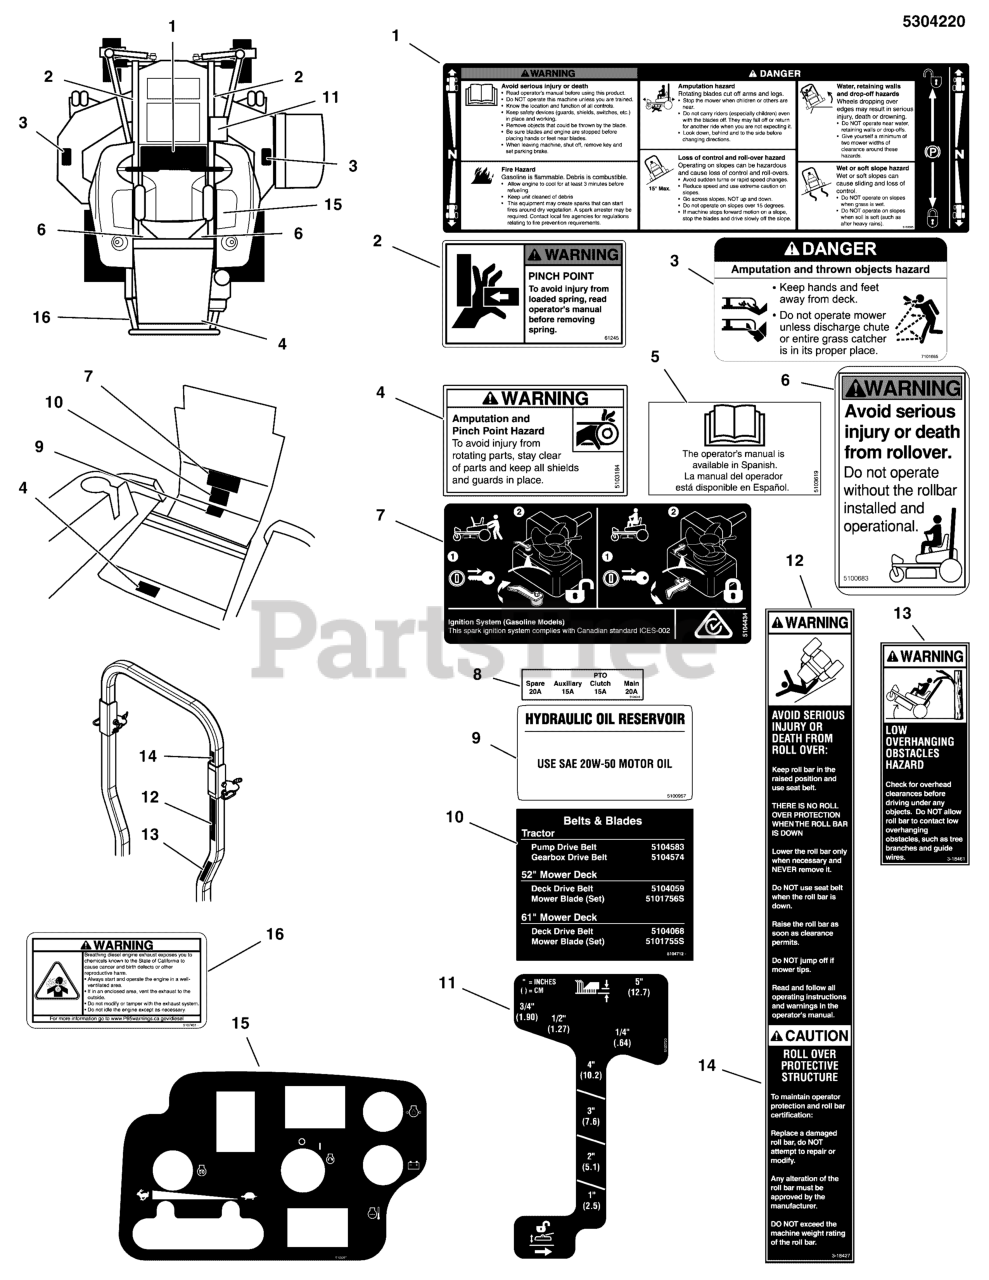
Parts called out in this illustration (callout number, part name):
1	DECAL, MAIN SAFETY
2	DECAL, Pinch Point
3	DECAL, DANGER DO NOT OPERATE W/O DEFLECT
4	DECAL, WARNING, HAND IN BELT, ENG ONLY
5	DECAL, MANUAL AVAILABLE IN SPANISH
6	DECAL, Warning, ROLL BAR
7	DECAL, TRANSAXLE RELEASE, ZT4400
8	DECAL, FUSE LOCATION, 20-15-15-20
9	DECAL, HYDRAULIC OIL, SAE 20W50
10	DECAL, BELT & BLADE, IS2600
10	DECAL, BELT & BLADE, IS2600Z (2017)
11	DECAL, CUT HEIGHT, IS700/ZTS700
12	DECAL, WARNING, FOLDING ROLL BAR
13	DECAL, WARNING OVERHANG, ROPS (SV)
14	DECAL, CAUTION, FOLDING ROLL BAR
15	DECAL, CONTROL PANEL, S2500Z, 3 POS IGN
16	DECAL, WARNING, PROP 65 DIESEL
